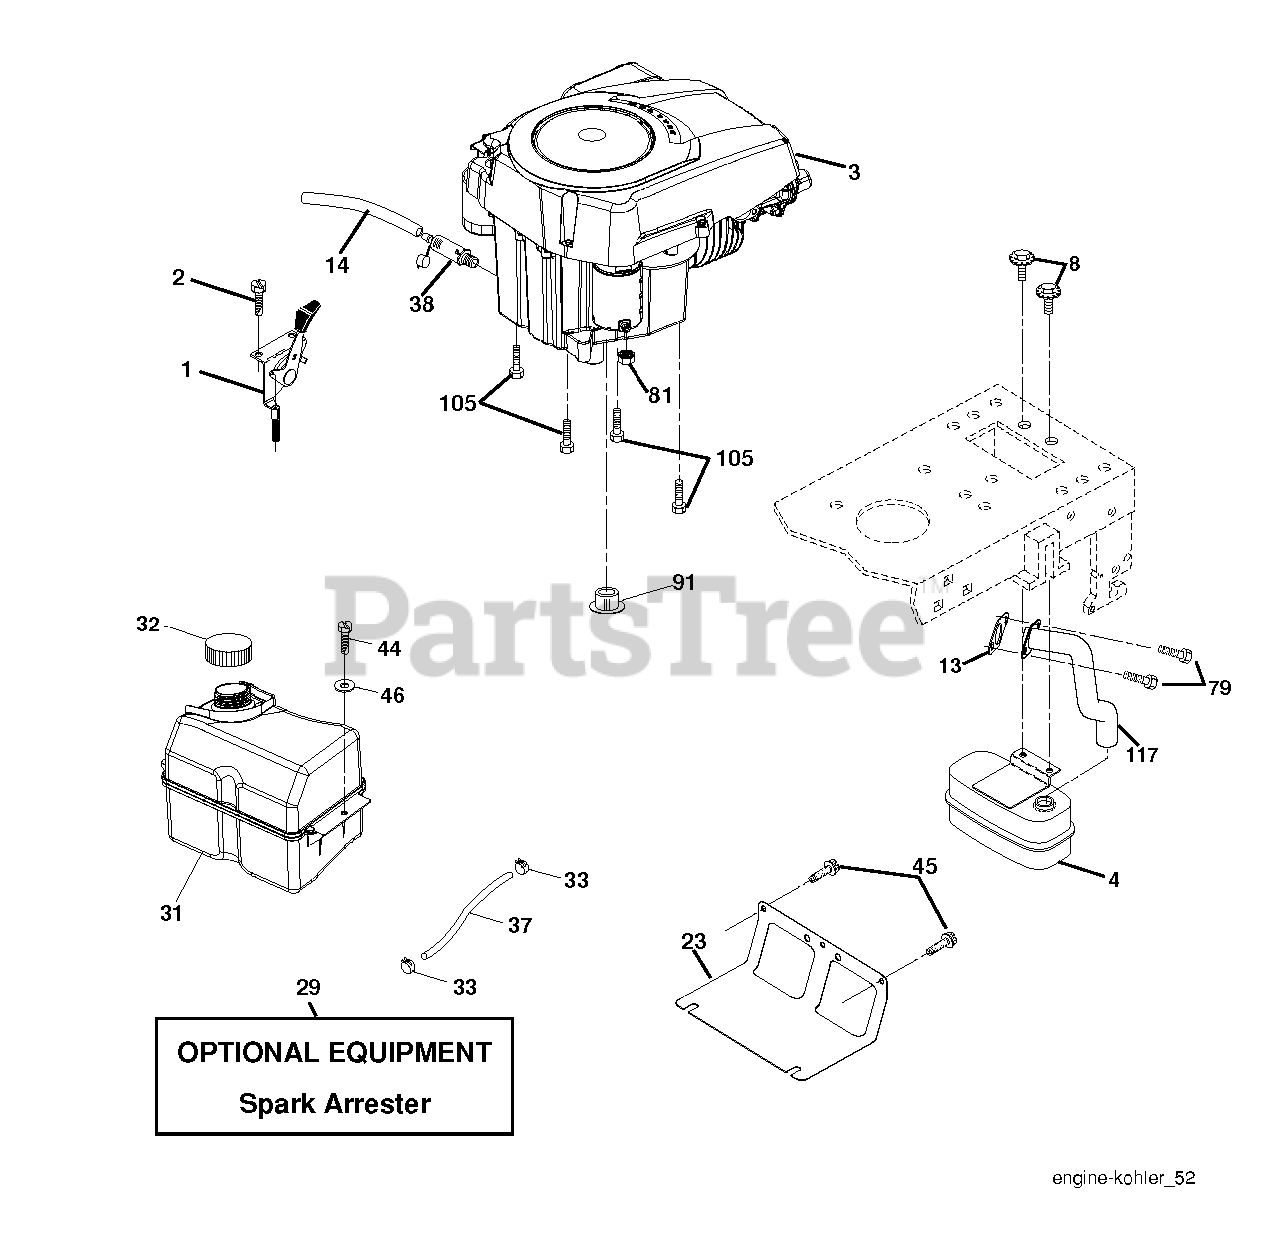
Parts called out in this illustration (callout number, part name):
1	CONTROL.TH/CK.C.
2	SCREW.#10 X 0.750.BOS
4	MUFFLER.SINGLE.CYL.KOHL/B&S
8	BOLT.5/16-18UNCX3/4 W/SEMS.BLK
13	GASKET.EXHAUST.KOHLER
14	TUBE, DRAIN OIL ASM.
23	SHIELD.BROWNING.DBR.GUARD
29	KIT.SPARK ARRESTOR 794945 B&S
31	RP TANK FUEL FRT 1.5 GAL
32	FUEL CAP
33	HOSE CLAMP
37	LINE.FUEL.20
38	PLUG DRAIN OIL EASY
44	SCREW HEXWSHR 1/4-20X3/4
45	SCREW, 3/8-16X3/4
79	SCREW.SOCKET HD.5/16-1
81	NUT
91	BUSHING.1.375OD
105	SCREW 3/8-16X1
117	RP.TUBE.EXHAUST.KOHL.COURAGE
